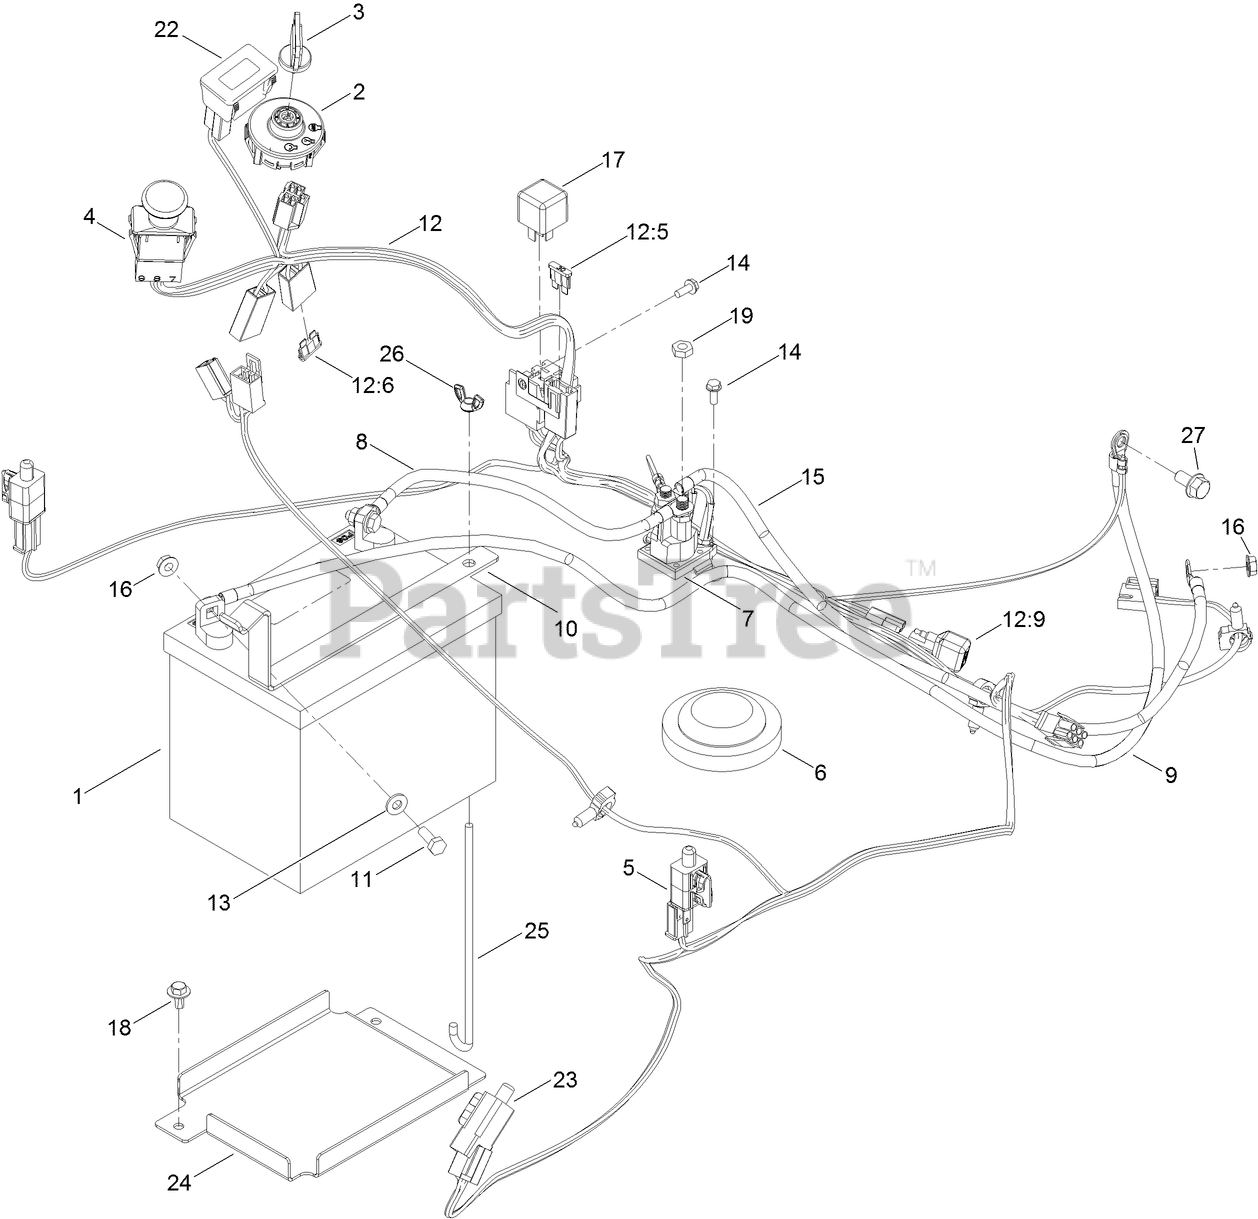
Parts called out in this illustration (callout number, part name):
1	BATTERY
3	KEY-IGNITION
4	SWITCH-PTO
5	SWITCH
6	SWITCH-SEAT
7	SOLENOID
8	CABLE-BATTERY, POSITIVE
9	CABLE-BATTERY, NEGATIVE
10	STRAP-BATTERY
11	SCREW-HH
12	HARNESS-WIRE
12:5	FUSE-BLADE, 30 AMP
12:6	FUSE-BLADE, 25 AMP
13	WASHER-FLAT
14	SCREW-TAPTITE
15	WIRE-21 INCH
16	NUT-HF
17	RELAY
18	SCREW-HHFTF
19	NUT-JAM
22	HOURMETER
23	SWITCH-REVERSE
24	TRAY-BATTERY
25	BOLT-HOLDDOWN
26	WINGNUT
27	SCREW-HHF
